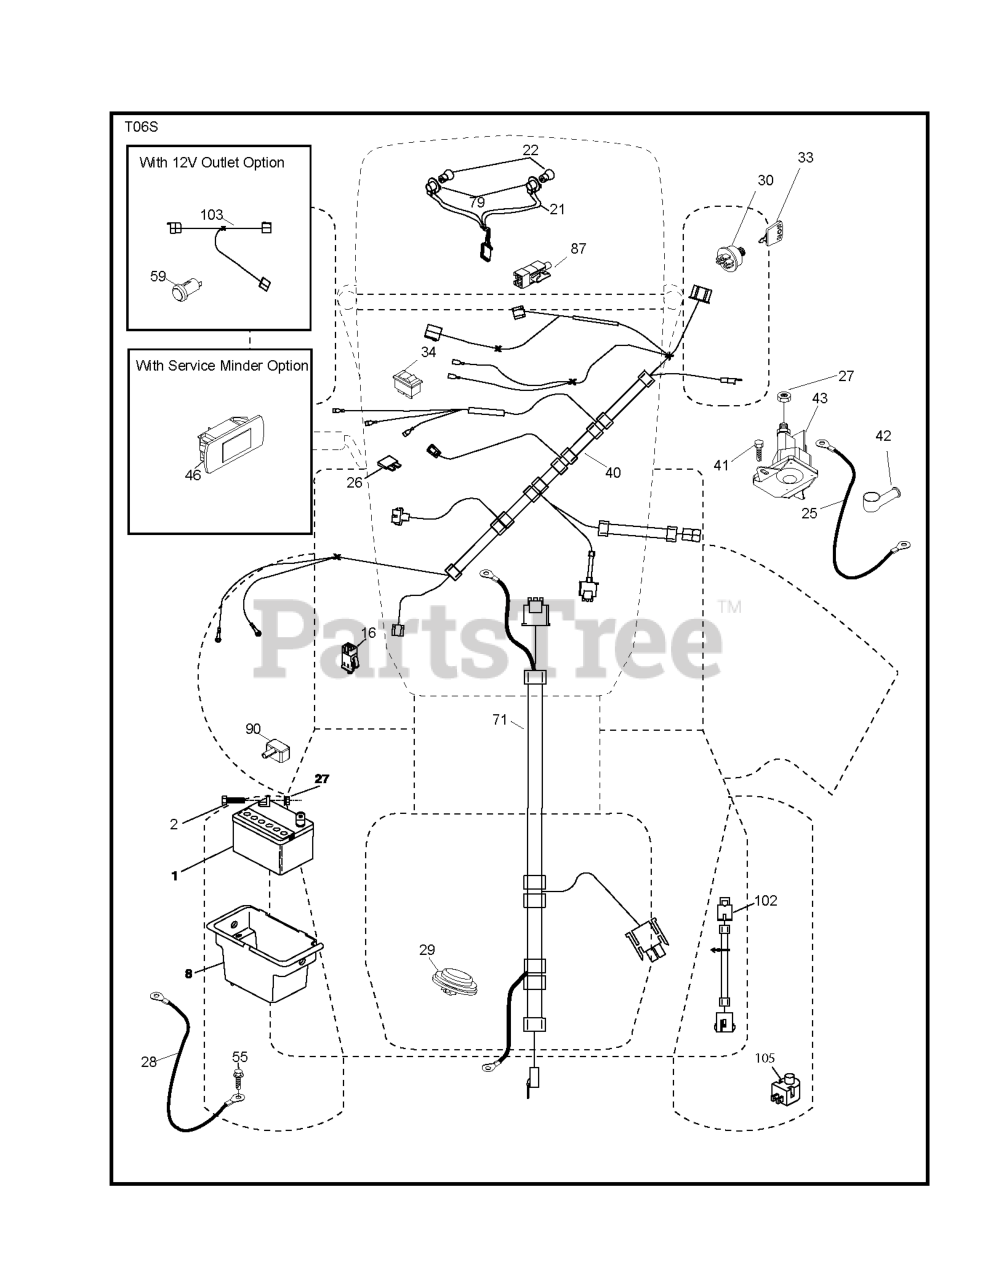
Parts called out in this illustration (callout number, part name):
1	Battery 12 Volt 25 Amp
2	BOLT.HEX.1/4.X.3/4.DICHROMATE
8	BOX.BATTERY.MNT.REAR.L
16	SWITCH INTERLOOK PUSH-IN
21	HARNESS ASSY LIGHT
25	CABLE.STARTER.6G.BL/RED.17.5
26	FUSE 20AMP
27	NUT
28	CABLE.BLACK.18"REAR.BA
29	SWITCH.SEAT.DELTA.OPC.
30	SWITCH.IGN.DELTA.W.LGH.ROS
33	KEY.CHAIN.BLISTER.PACK.GEN.USA
40	HARNESS IGN. DASH
41	SCREW
42	TERMINAL COVER
43	SOLENOID.W/BRASS.PLUNGER
46	RP.GUAGE.SRVCMNDR.HRMTR.
55	SCREW 5/16"
71	HARNESS.IGN.CHASS.TEX.REAR.BAT
79	BULB HOLDER ASM.
87	SWITCH.INTRLCK.CLUTCH.
90	COVER, TERMINAL BATTERY
102	HARNESS PIGTAIL PCH TEX ROS
105	REVERSE SWITCH
